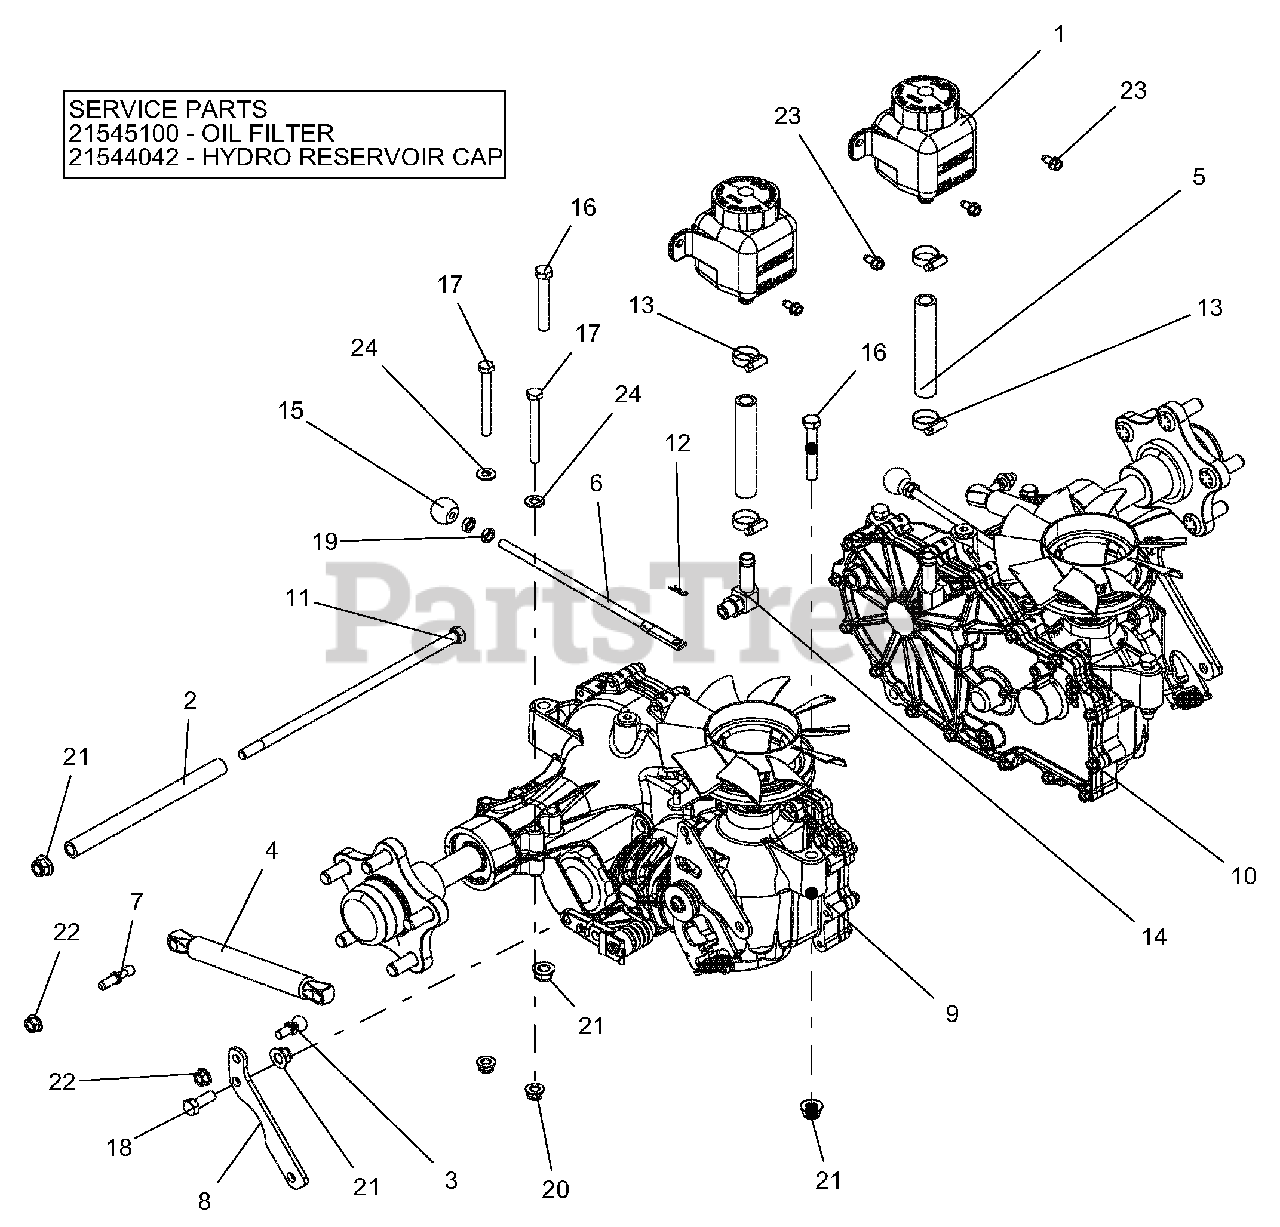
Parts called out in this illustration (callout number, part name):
1	TANK, EXPANSION ZT2800
2	SPACER, .406 ID X .630 OD X 7.724
3	STUD-BALL
4	DAMPER,
5	HOSE, PT100 HYDRO OVERFLOW
6	LEVER, PT100 DUMP VALVE
7	STUD, BALL THREADED
8	TRANSMISSION DAMPER MTG PLATE - BLK
9	TRANSAXLE, 3200 SERIES - RH
10	TRANSAXLE, 3200 SERIES - LH
11	BLT, HEX .38-16X11.00 GR5 CYWZ
12	PIN-HAIR INT .06X.18X.77
13	CLAMP, .88 DIA HOSE
14	FITTING, HYD (90 DEG)
15	KNOB, BALL -BLACK .312-18
16	BLT-HEX .38-16X2.50 GR5 YWZC
17	BLT-HEX .31-18X3.00 GR5 YWZC
18	BLT-HEX .38-16X1.00 GR5 YWZC
19	NUT, JAM .312-18 YWZC
20	NUT-LK-NYL-FLG .31-18 YWZC
21	NUT-LK-NYL-FLG .38-16 YWZC
22	NUT, LK-TOP-FLG .312-18 YWZ
23	SCR-TAP .25-20X.50 HWH TR YWZC
24	WSHR-FL-STL.344X.688X.065YWZC
